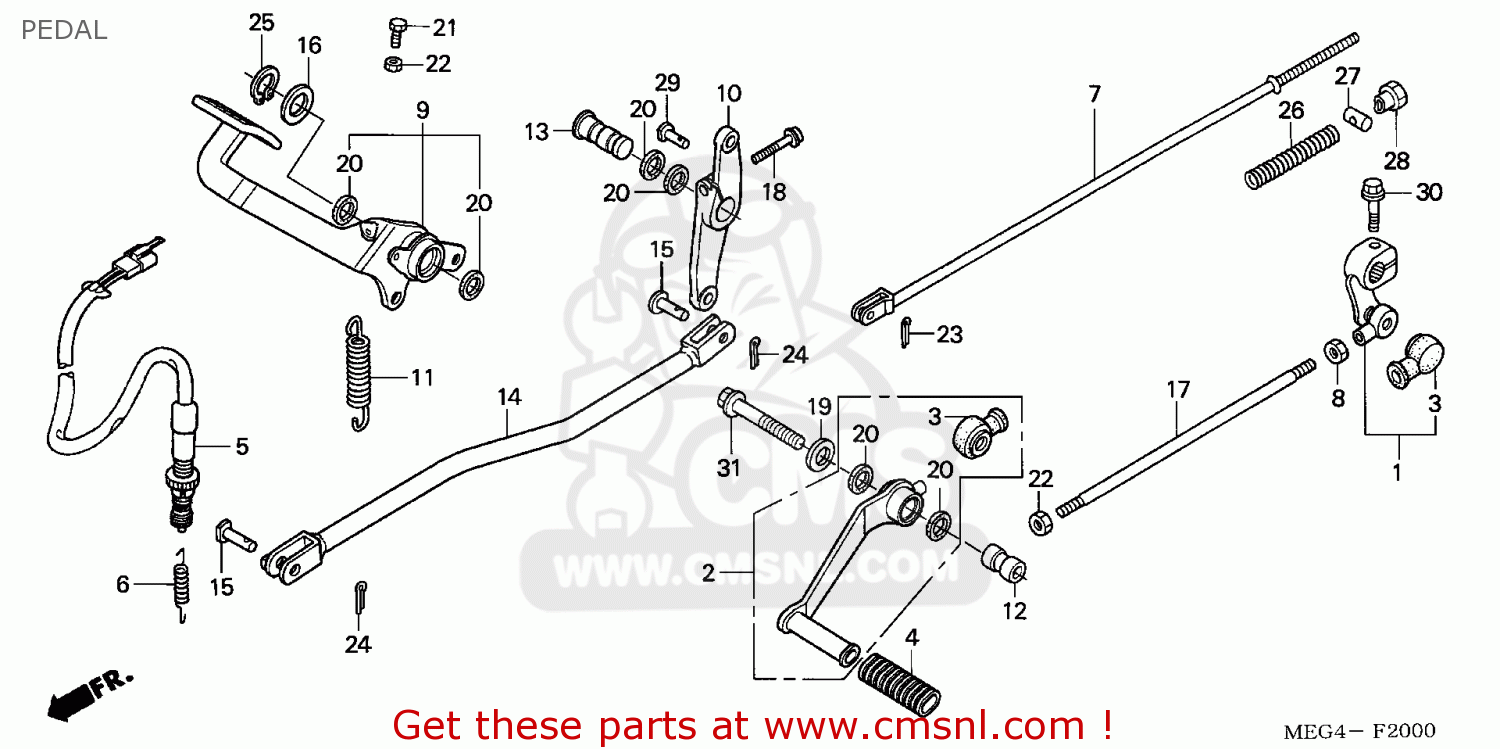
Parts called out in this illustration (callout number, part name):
1	ARM COMP,CHANGE
2	PEDAL COMP,CHANGE
3	COVER,DUST
4	RUBBER,CHANGE
5	SW ASSY,REAR STOP
6	SPRING,STOP SW.
7	ROD COMP,RR BRK
8	NUT,HEX.,6MM
9	PEDAL ASSY,RR BRK
10	ARM,RR BRAKE MIDD
11	SPRING,BRAKE PEDA
12	COLLAR,RR.BRAKE P
13	SHAFT,RR BRAKE PI
14	ROD,RR BRK MIDDLE
15	PIN,MID ROD JNT
16	BUSH,WASER
17	BOLT,TIE ROD
18	BOLT,FLANGE SOCKE
19	WASHER,10.3MM
20	SEAL,DUST 17X23X3
21	BOLT,HEX.,6X20
22	NUT,THIN 6MM
23	PIN,SPLIT2.0X12
24	PIN,COTTER 2.0X15
25	CIRCLIP,EX. 15MM
26	SPG.A,BRAKE ROD
27	JOINT, BRAKE ARM
28	NUT,ADJUST
29	PIN C,JOINT
31	BOLT,FLANGE,10X50
